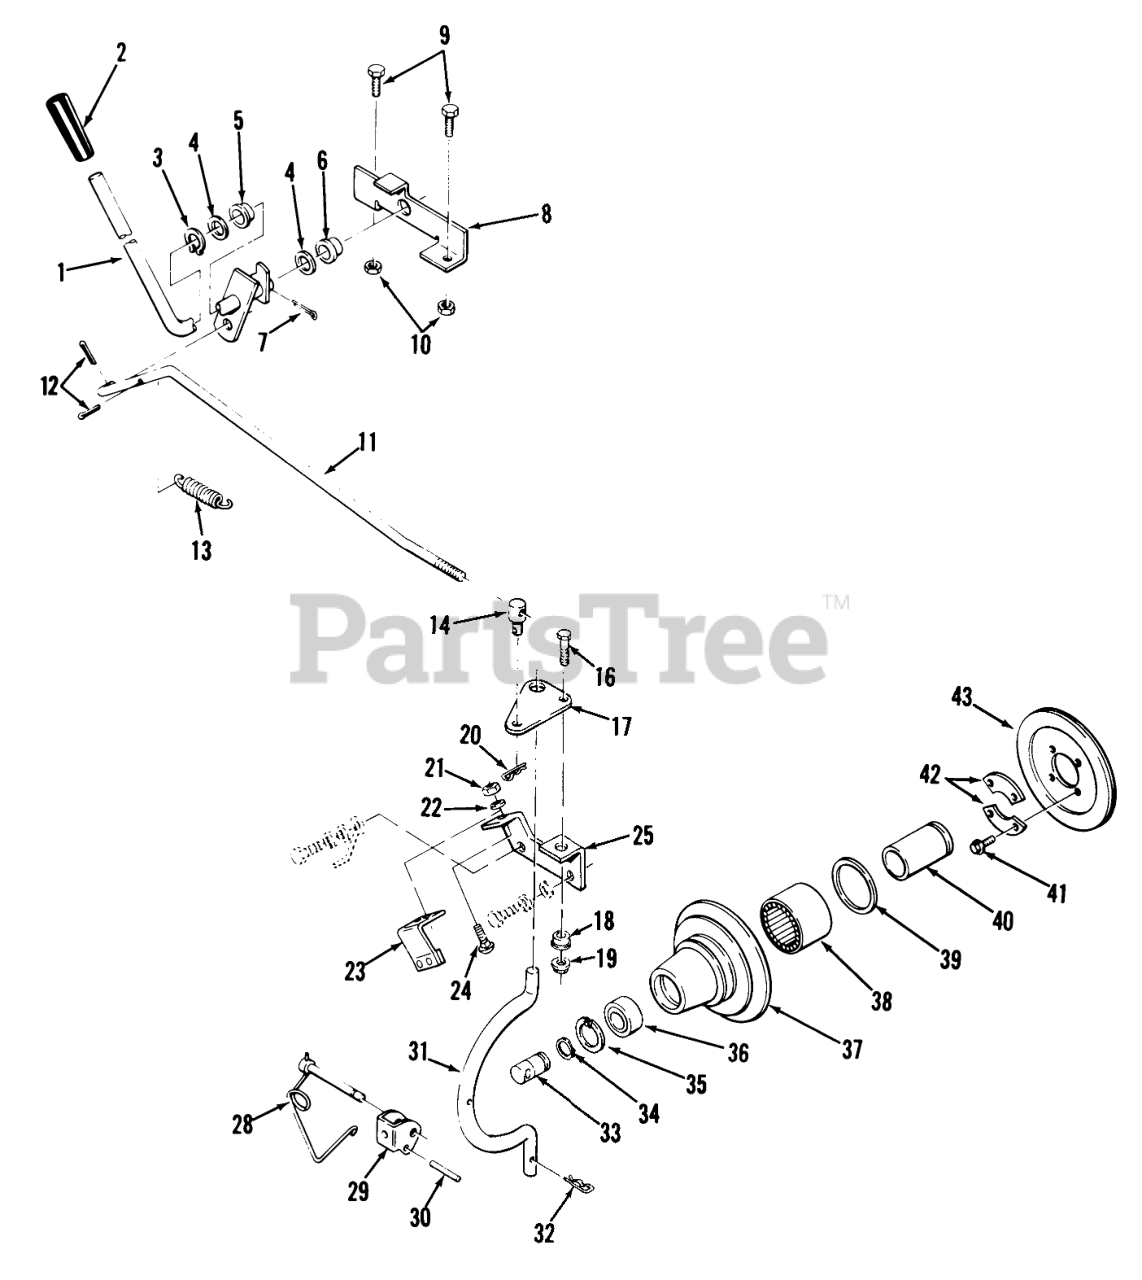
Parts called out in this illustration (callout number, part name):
1	PTO CLUTCH LVR ASM
2	GRIP
3	Grip Ring
4	SHIM-WASHER
5	BUSHING-NYLINER
6	NYLINER BUSHING
7	Pop Rivet
8	SUPPORT-PTO CLUTCH
9	Bolt
10	Nut
11	PT0 Clutch Rod
12	Pop Rivet
13	SPRING
14	TRUNNION
16	BOLT
17	PLATE R
18	SPACER-LIFT LINK
19	Nut
20	Hairpin Cotter
21	Nut
23	PTO Brake Assy
23	PTO Plate
24	Bolt-Carriage
25	BRACKET-ENGINE B
25	BRACKET
28	Pin
29	Clevis
31	ROD-HOUSING
32	Hairpin
33	SHAFT-PTO
34	RING-SNAP, EXTERNAL
35	Ring-Snap
36	BaIl Bearing
37	Housing-Clutch
38	BRG-NEEDLE OPEN END
39	SEAL-OIL
40	BEARING RACE
40	RACE-BEARING
41	Screw
42	RETAINER
43	Clutch Plate & Facing
